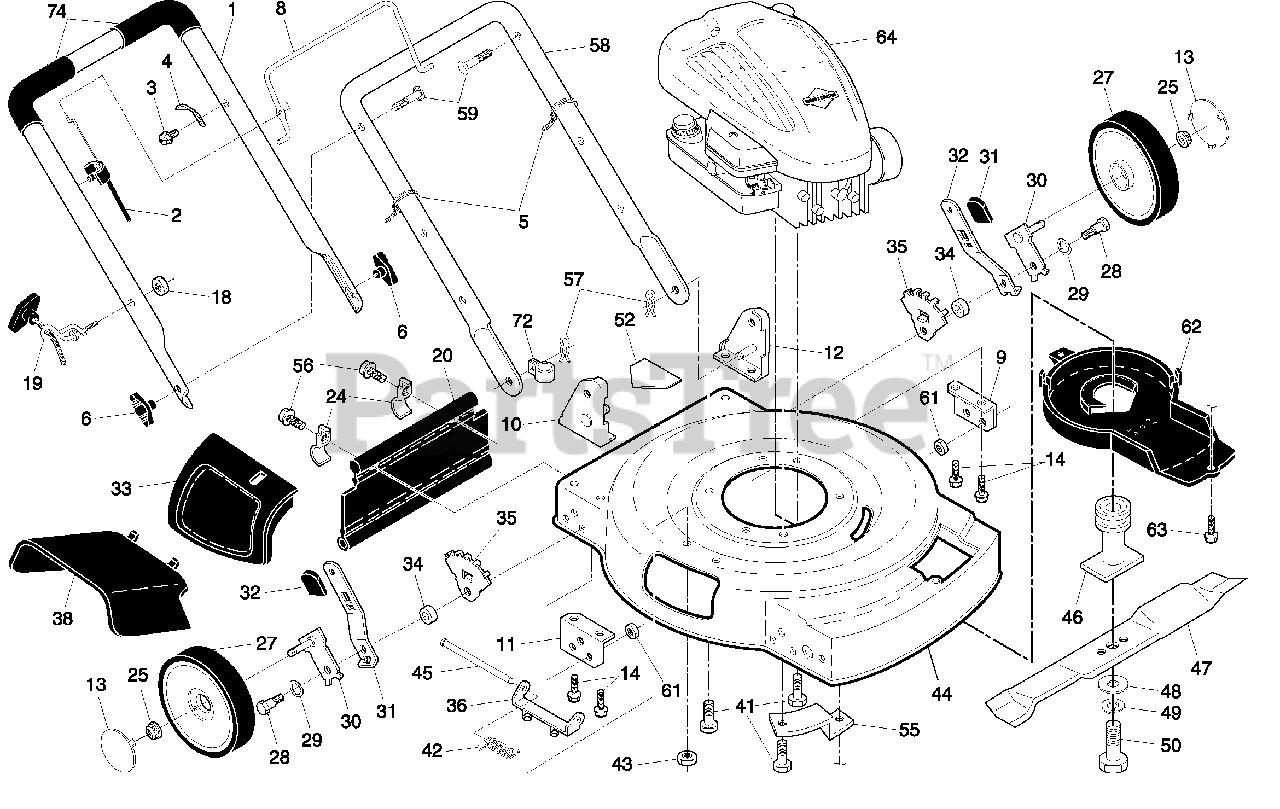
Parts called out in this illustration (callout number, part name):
1	Upper Handle Assembly
2	Engine Zone Control Cable
3	Screw
4	Bracket, Upstop
5	Wire Tie
6	Handle Knob
8	Control Bar
9	Support Bracket, Handle, LH
10	Handle Bracket, RH
11	Support Bracket, Handle, RH
12	Handle Bracket, LH
13	Hubcap
14	Screw, Thread Cutting 5/16-18 x 3/4
18	Locknut, Keps
19	Rope Guide
20	Kit, Rear Skirt
24	Clamp, Rear Skirt
25	Locknut, Hex 3/18-16
27	Wheel & Tire Assembly
28	Shoulder Bolt
29	Washer, Curved, Cylindrical
30	Axle Arm Assembly
31	Knob, Selector
32	Spring, Selector
33	Mulcher Door
34	Spacer
35	Bracket, Wheel Adjuster
36	Bracket, Housing
38	Deflector, Discharge
41	Screw, Hex Head, Threaded, Rolled 3/8-16 x 1-1/8
42	Spring, Torsion
43	Locknut, Hex 1/4-20
44	Kit, Mower Housing
45	Rod, Hinge
46	Blade Adapter / Pulley
47	Blade, 22"
48	Washer, Hardened
49	Washer, Lock, Helical
50	Screw, Hex Head, Grade 8 3/8-24 x 1-3/8
52	Decal, Danger
55	Mounting Bracket, Debris Shield
56	Screw, Hex Washer Head #10-24 x 1/2
57	Hairpin Cotter
58	Lower Handle
59	Handle Bolt
61	Locknut, Hex
62	Debris Shield
63	Screw
72	Clip, Cable
74	Grip, Foam
74	Operator's Manual, English
74	Operator's Manual, French
74	Repair Parts Manual
